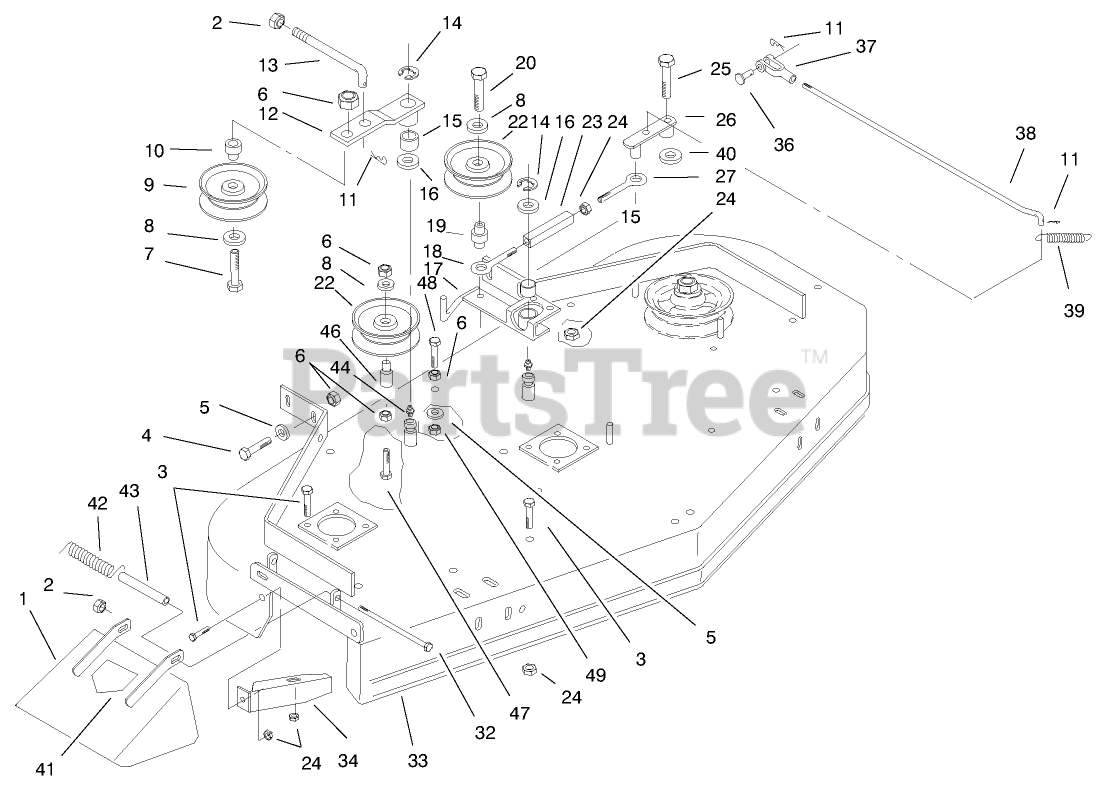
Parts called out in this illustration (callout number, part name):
1	Chute-Discharge
2	NUT-LOCK, NI
3	Screw-HH
4	SCREW-HH
5	Washer
6	NUT-FLANGE
7	SCREW-HH
8	WASHER-FLAT
9	Pulley-Idler
10	Bushing
11	PIN-COTTER
12	Idler Arm Assembly
13	Rod-Tension
14	Ring-Snap
15	Bearing
16	Spindle Washer
17	Engagement Arm w/Bushing
18	Eye Bolt
19	Bushing
20	Bolt-Whizlock
22	Pulley-Idler
23	Turnbuckle Body
24	NUT-HF
25	Bolt-Shoulder
26	Assist Arm ASM
27	Eye Bolt
32	Screw-HH
33	Deck ASM w/ Decals
34	Baffle Weldment
36	Pin-Clevis
37	Yoke
38	Linkage-Assist Arm
39	Spring-Extension
40	WASHER-THRUST
41	DECAL-DANGER
42	Spring-Deflector
43	Spacer-Spring
44	FITTING-STRAIGHT
46	Bushing
47	TAP Bolt
48	SCREW-HH
49	NUT-HEX
